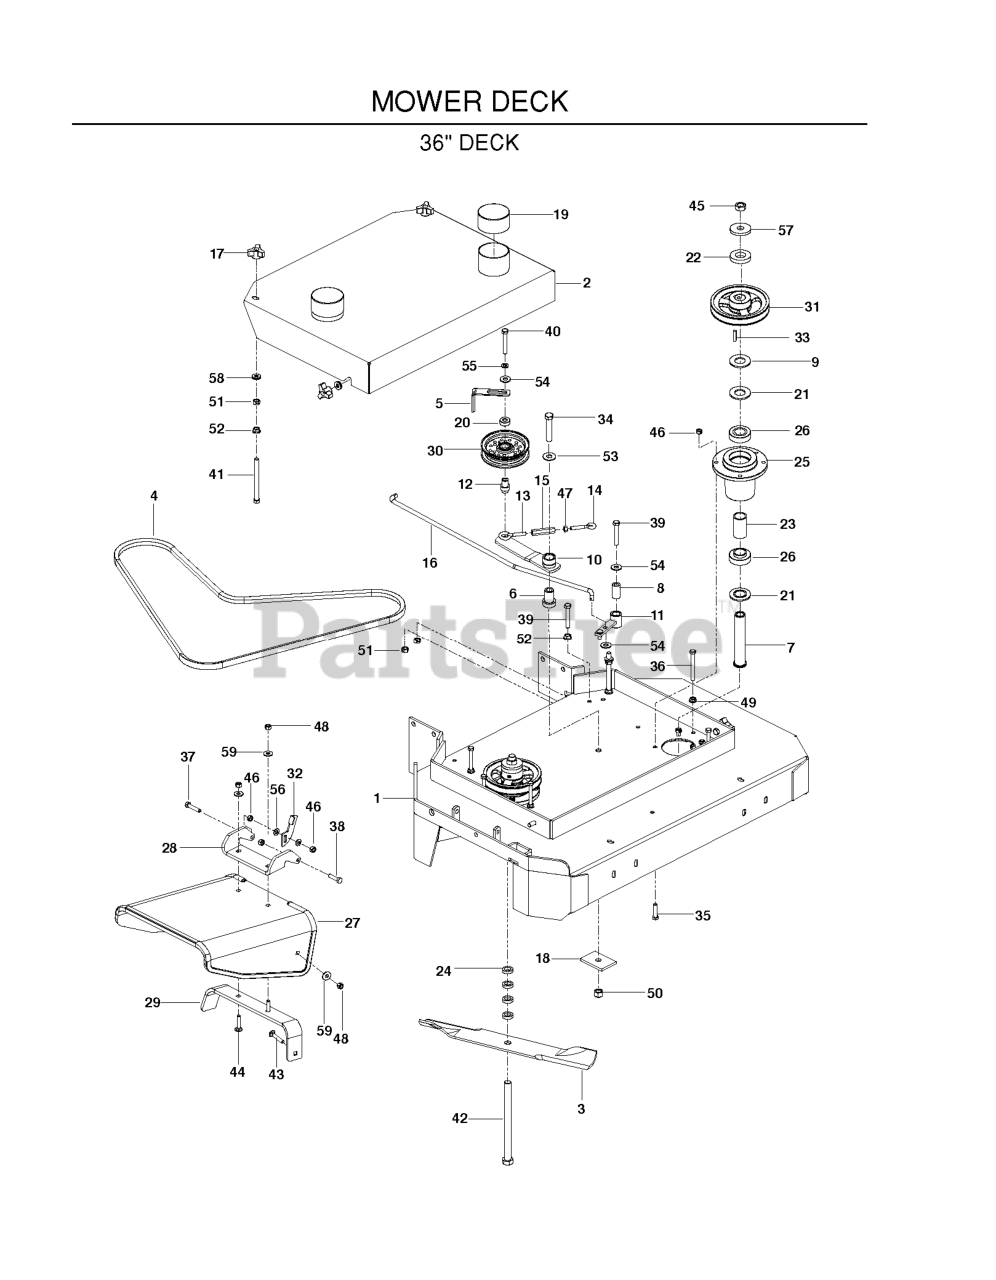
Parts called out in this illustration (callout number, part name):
1	DECK W/DECALS 36"
2	BELT SHIELD ORANGE 36"
3	BLADE OEM 18"
4	BELT, DECK, 36"
6	IDLER SPINDLE
7	SPINDLE SHAFT
8	BUSHING, SLEEVE
9	MACHINERY BUSHING 10 GA.
10	ARM WELDMENT
11	ENGAGEMENT ARM
12	EYEBOLT PIVOT
13	EYEBOLT, LH
14	EYEBOLT, RH
15	TURNBUCKLE
16	BLADE ROD 36"
17	KNOB, THREE PRONG
21	COMBO SPACER
24	BLADE SPACERS
25	HOUSING, DIE CAST
26	BEARING-ECC LOCK W/COLLAR
27	CHUTE, RUBBER DISCHARGE WB
28	PIVOT BRACKET - CHUTE
29	BRKT, REINF-CHUTE WB
30	IDLER PULLEY
31	PULLEY W/SETSCREWS
32	STOP, CHUTE - BLACK
33	KEY 1/4 SQ X 1 1/8
34	HCS 1/2C X 2 3/4
35	HCS 5/16C X 1
36	HCS 5/16 X 3
37	CAPSCREW 5/16 X 1/1/2 HEX HEAD
38	HCS 5/16C X 1 1/4
39	HCS 3/8C X 2 1/4
40	HCS 3/8C X 2 1/2
41	TAPBOLT 3/8C X 4 1/2
42	HCS 5/8F X 8 1/2
43	BOLT, CARRIAGE 5/16X1-1/4
44	RHSNB 5/16-18 X 1-1/2 GR 5 ZD
45	NUT 5/8F HEX
46	NUT 5/16C CENTERLOCK
47	NUT 5/16C HEX
48	NUT 5/16 NYLOC
49	NUT 5/16C WHIZ
50	NUT 1/2-13 HEX NYLOC ZD
51	NUT 3/8C CENTERBLOCK
52	NUT 3/8C WHIZ
53	WASHER 1/2 FLAT
54	WASHER 3/8 FLAT
55	SLW 3/8 STD
56	FLAT WASHER 5/16 SAE
57	WASHER, SUPPORT
58	WASHER, 3/8 SEALING
59	WASHER 5/16 FLAT
